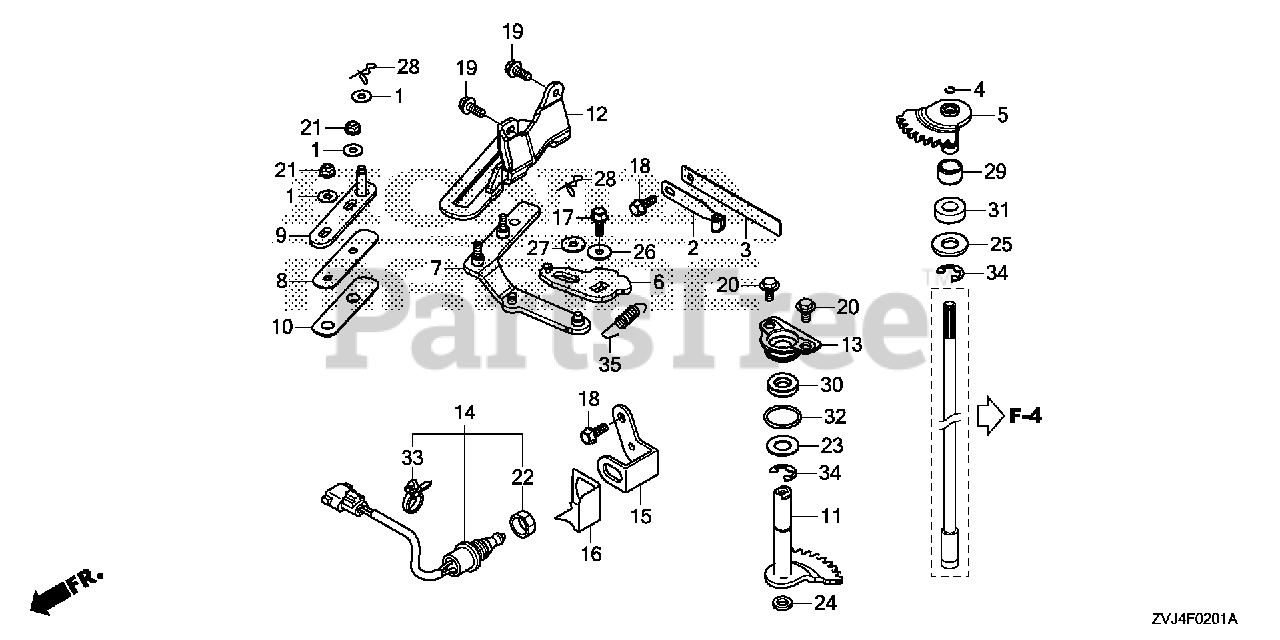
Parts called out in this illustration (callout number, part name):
1	WASHER, PIVOT
2	SPRING, CLICK
3	SPRING, CLICK ASSIST
4	RING, STOPPER
5	SHAFT, SHIFT (A)
6	ARM, SHIFT
8	PLATE, SHIFT PIVOT
9	ROD, ACTUATOR LINK
10	PIVOT, SHIFT SLIDE
11	SHAFT, SHIFT (B)
12	GUIDE, SHIFT LINK
13	HOLDER, SEAL
14	SWITCH ASSY., NEUTRAL
15	BRACKET, NEUTRAL SWITCH
16	COVER, NEUTRAL SWITCH
17	BOLT, FLANGE (6X16)
18	BOLT, FLANGE (6X14)
19	BOLT, FLANGE (8X20)
20	BOLT, FLANGE (6X11)
21	NUT, SELF-LOCK (6MM)
22	NUT, HEX. (20MM) Use up to Frame SN 1300359.
23	WASHER, THRUST (14MM)
24	WASHER B, THRUST (14MM)
26	WASHER, PLAIN (6MM)
27	WASHER, PLAIN (6MM)
28	PIN, SNAP (6MM)
29	RING (INNER) (15X20X13)
30	OIL SEAL (14X26X6)
31	SEAL, WATER (14X26X8)
32	O-RING (26.9X2.4) (NOK)
33	CLIP, HARNESS BAND (145MM) (BLACK)
34	E-RING (12MM)
35	SPRING, GEARSHIFT ARM
